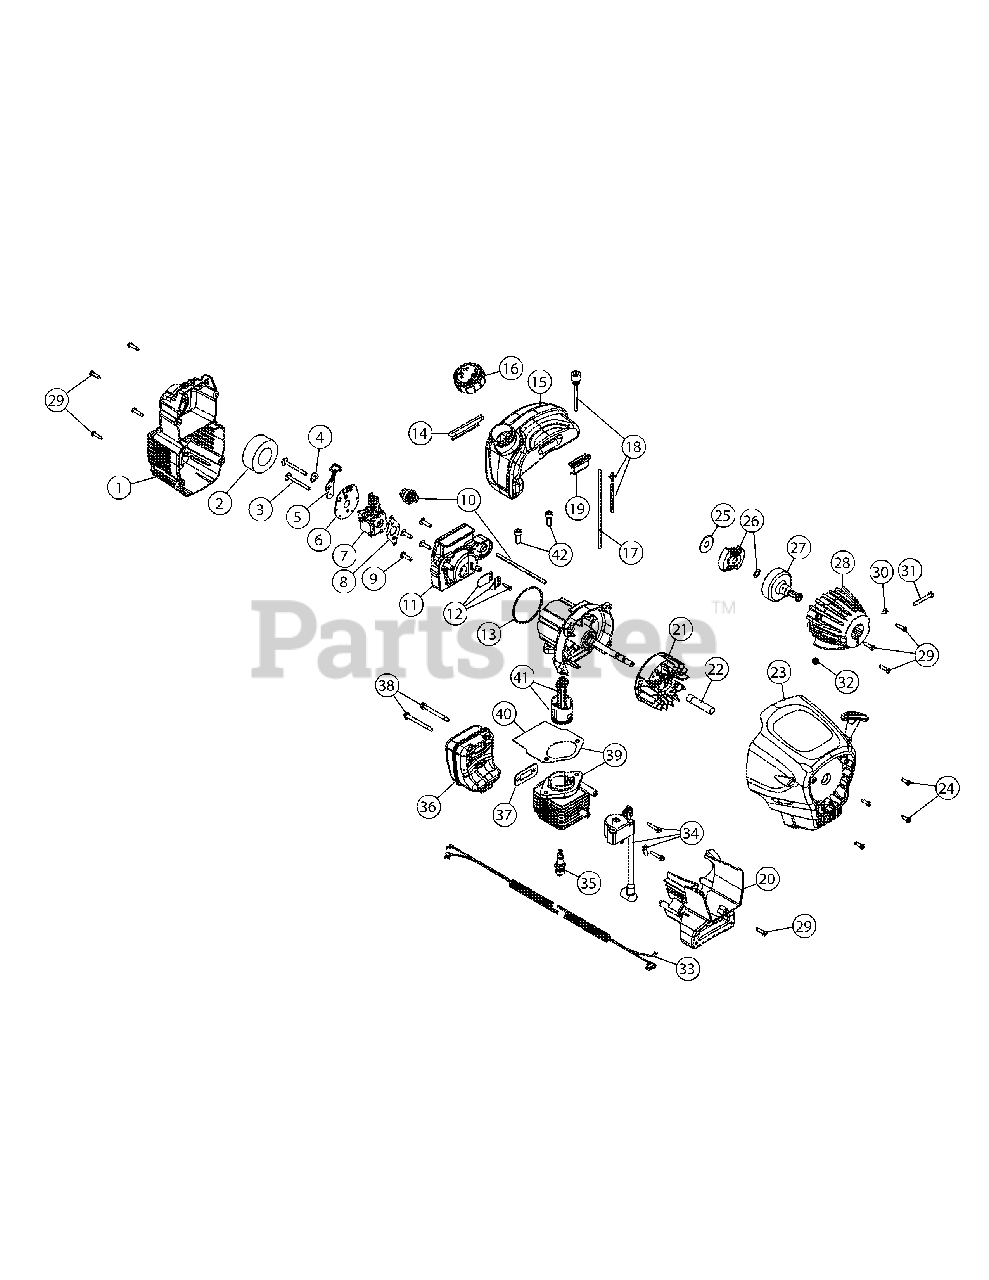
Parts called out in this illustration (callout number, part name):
1	Air Cleaner Cover Assembly
2	Air Cleaner Filter
3	Carburetor Mounting Screw Assembly
4	Wavey Washer
5	Choke Lever Assembly
6	Choke Plate Assembly
7	Carburetor Assembly
8	Carburetor Gasket
9	Carb Mount Screw
10	Primer & Hose Assembly
11	Carb Mount Assembly
12	Reed Assembly
14	Rear Mounting Pad
15	Fuel Tank Assembly
16	Fuel Cap Assembly
17	Fuel Return Line
18	Fuel Line Assembly
19	Front Mounting Pad
20	Shroud Extension & Stand
21	Flywheel Assembly
23	Starter Housing Assembly
24	Housing Screw
25	Clutch Washer
26	Clutch Rotor Assembly
27	Clutch Drum Assembly
28	Clutch Cover Assembly
29	Cover Screw
30	Anti-Rotation Screw
31	Clamping Screw
32	Clamping Nut
33	Wire Leads and Sleeve
34	Module Assembly
36	Muffler Assembly
37	Exhaust Gasket
38	Muffler Mounting Bolts
39	Cylinder Assembly
40	Piston and Rod Assembly
41	Cylinder Gasket
42	Cylinder Bolt
